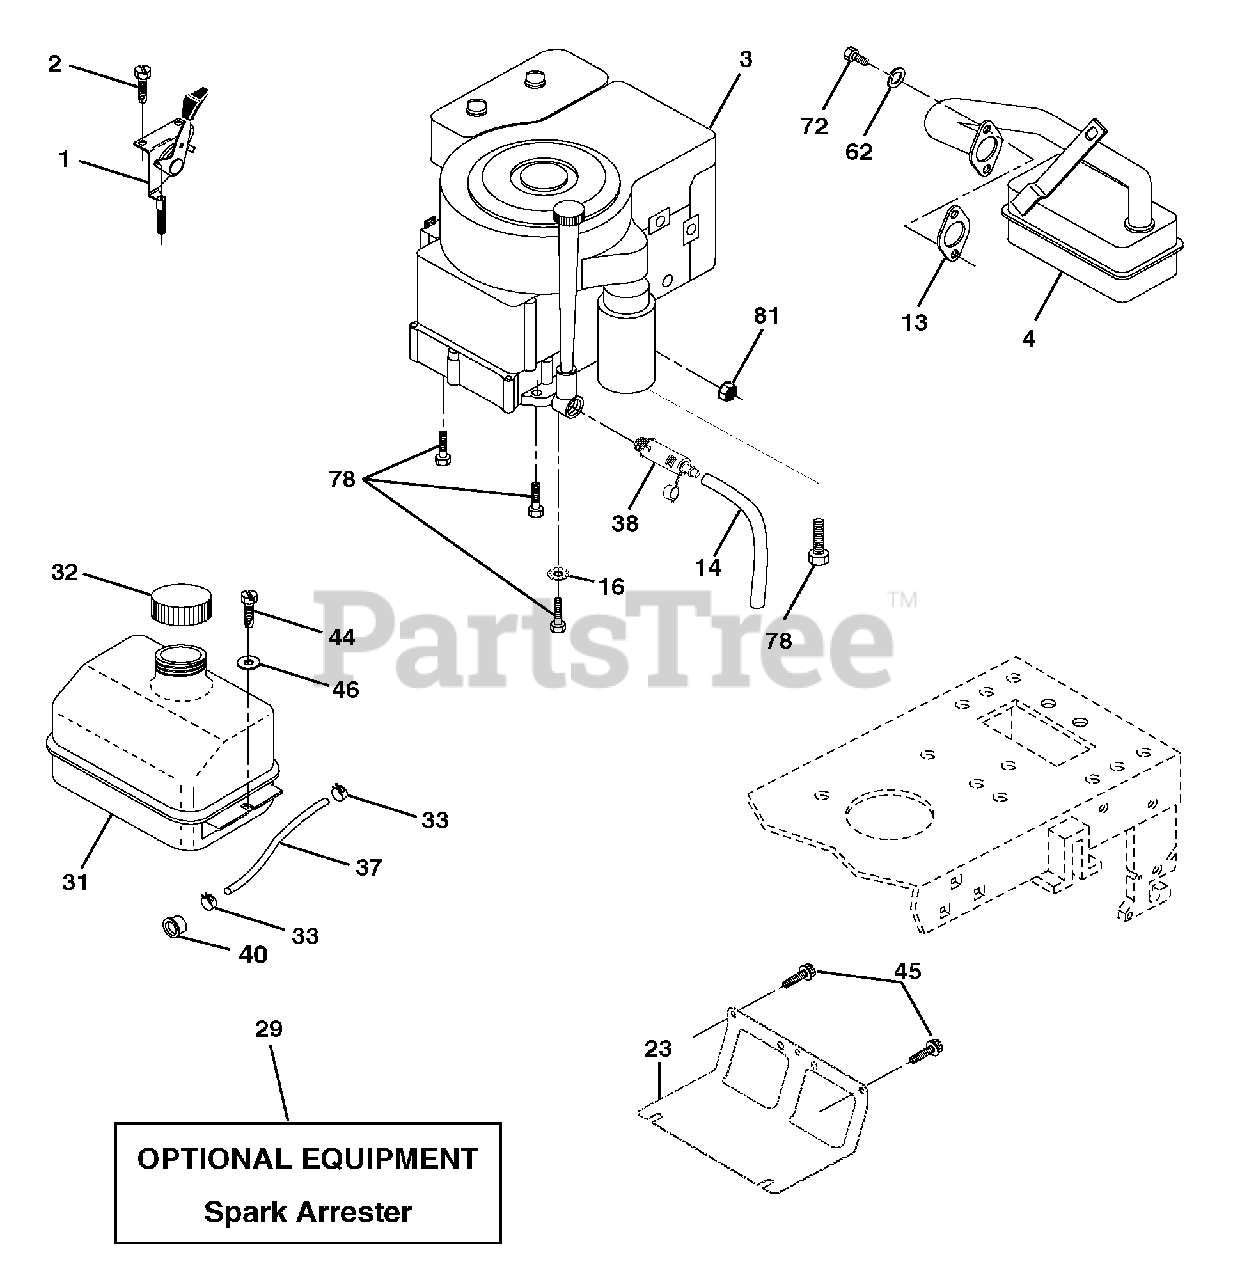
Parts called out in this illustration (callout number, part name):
1	Control Throt /Ch Flag
2	Screw Hex Thd Cut 1/4-20x1/2
4	Muffler Exhaust B&S Lt
13	Gasket 1 313 Id Tin Plated
14	Tube Drain Oil
16	Washer Lock Ext Tooth 3/8
23	Shield Browning/Debris Guard
29	Arrestor Spark
31	Tank Fuel 1 25 Fr
32	Cap Asm Fuel W/sym Vented
33	Clamp Hose Blk
37	Line Fuel 20"
38	Plug Drain Oil
40	Bushing Snap Nyl Blk Fuel Line
44	Screw Hexwsh Thdrol 1/4-20x3/4
45	Screw Hex Wsh Thdrol 3/8-16
46	Washer 9/32 X 7/8 X 16ga
62	Washer Lock Hvy Hlcl Spr 5/16
72	Screw Hexhd Cap 5/16-18x3/4
78	Screw 3/8-16x1-1/4
81	Nut Keps Hex 1/4-20 Unc
